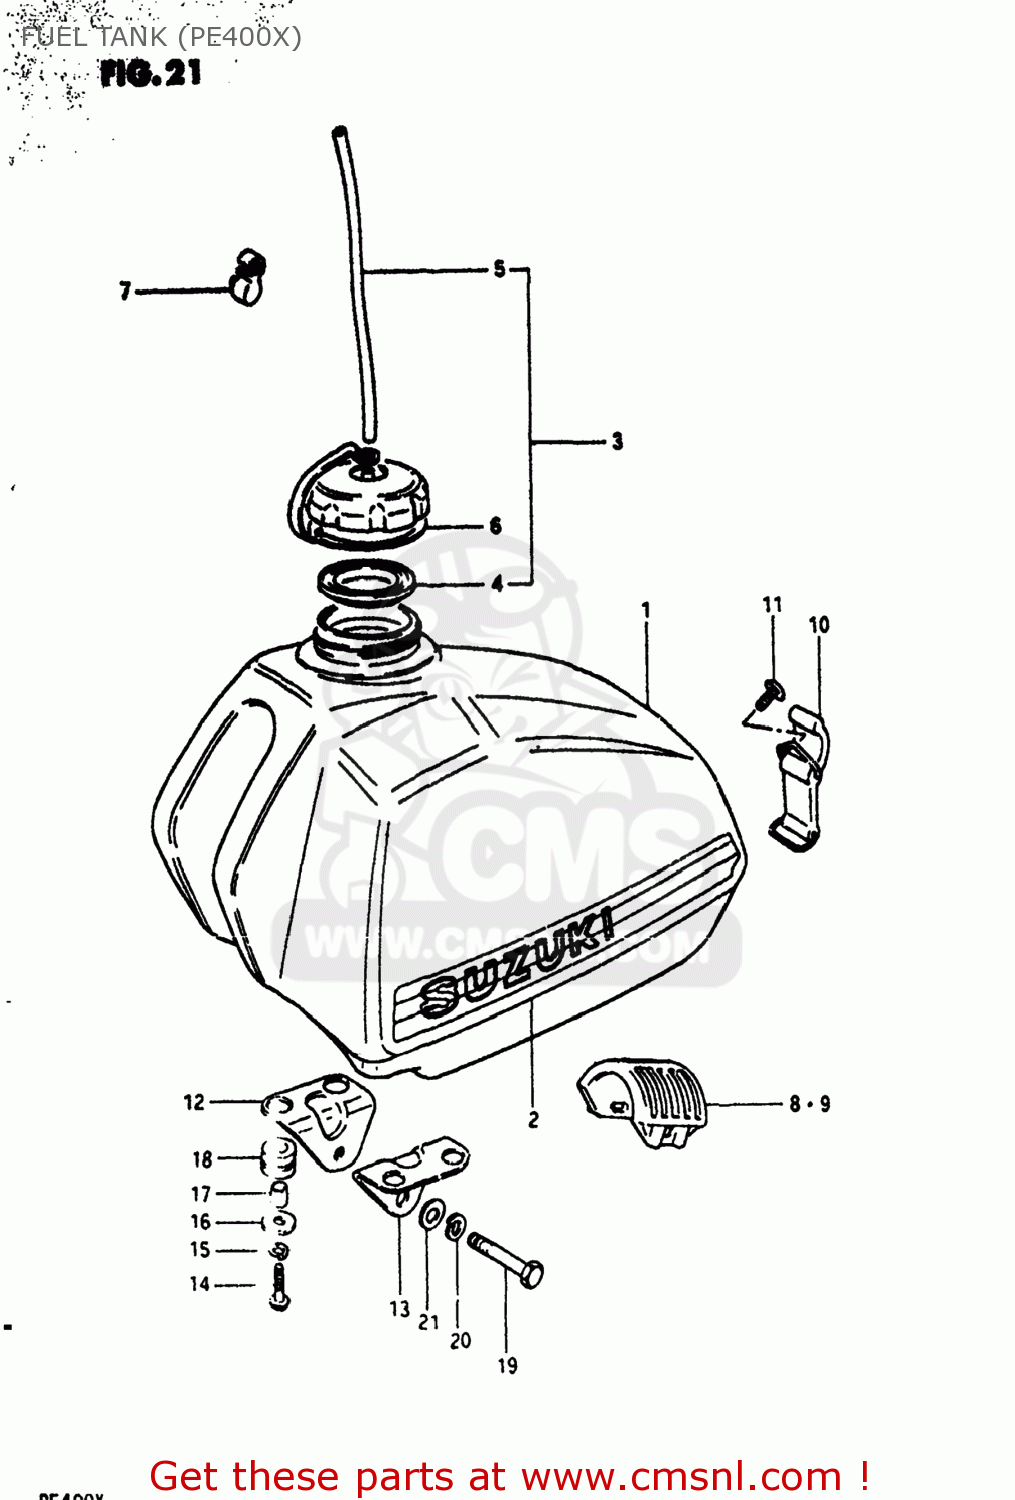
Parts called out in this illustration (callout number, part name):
1	TANK ASSEMBLY,FUEL
2	TAPE SET,FUEL TANK
3	CAP,FUEL TANK
4	GASKET,FUEL TANK CAP (NAS)
5	HOSE
6	BAND,FUEL TANK CAP
7	CLAMP,BREATHER HOSE
8	CUSHION,FUEL TANK
9	CUSHION,FUEL TANK UPR FR
10	BAND
11	SCREW(6X18)
12	BRACKET,FUEL TANK
13	BRACKET,FUEL TANK,LOWER
14	SCREW
15	LOCK WASHER
16	WASHER (6.5X24X1.6)
17	SPACER(6.8X12X11)
18	CUSHION
19	BOLT
20	LOCK WASHER
21	WASHER
